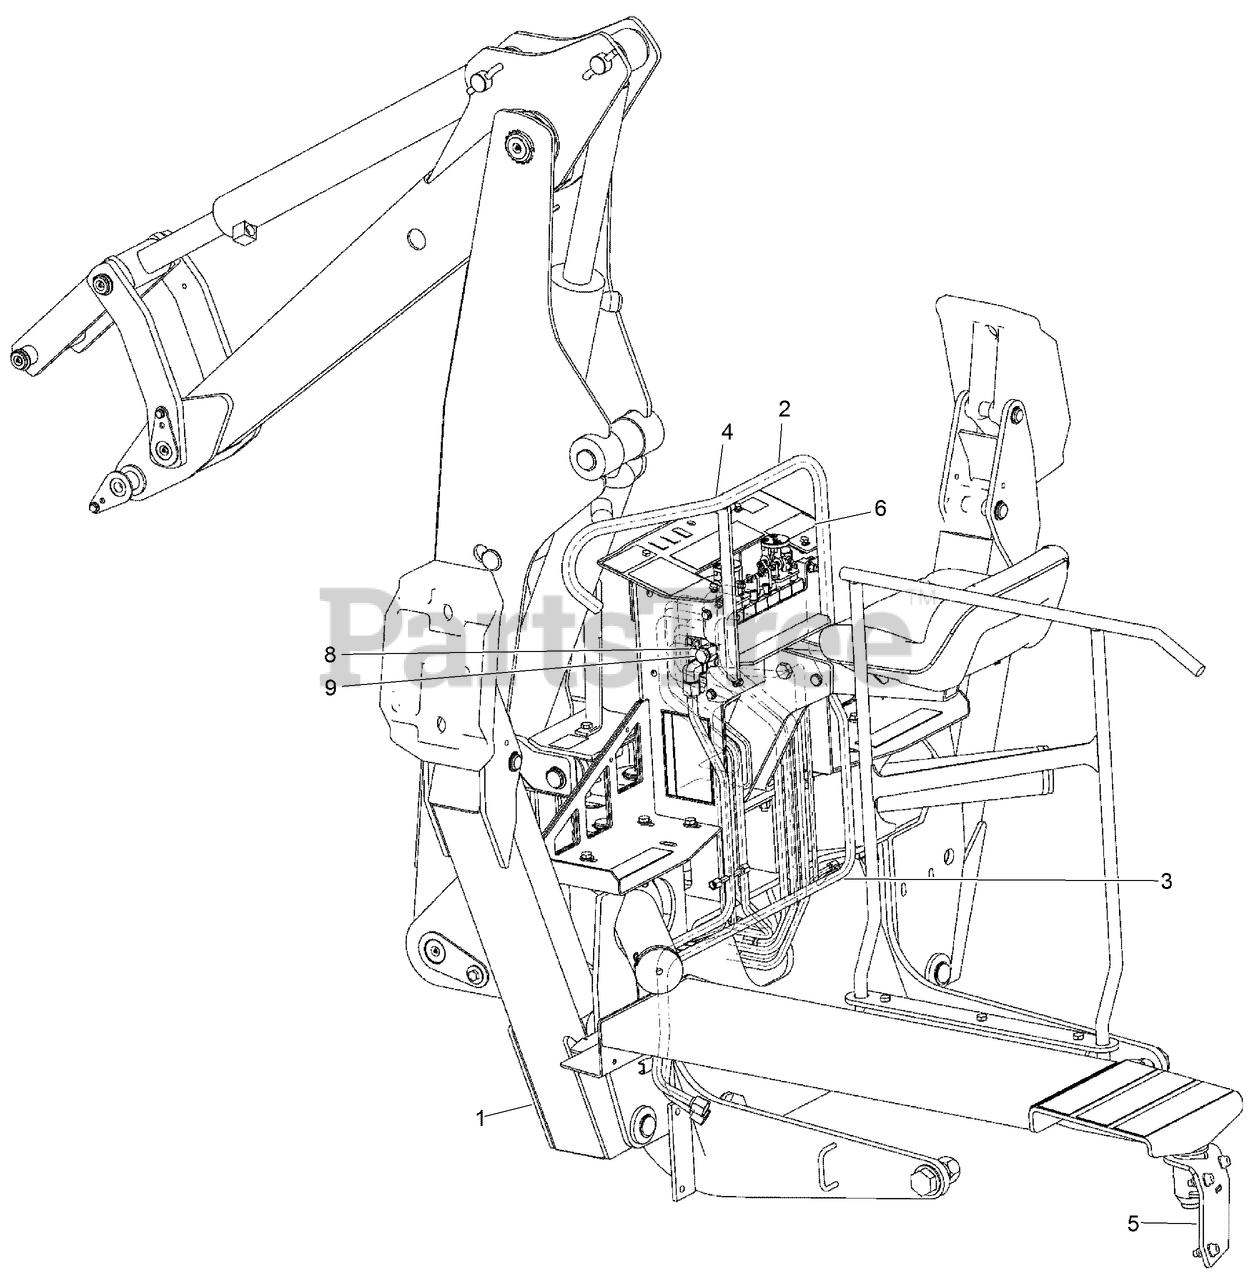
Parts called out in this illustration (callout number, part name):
1	ASSEMBLY - Basic Backhoe
2	ASSEMBLY - Backhoe Platform
3	KIT - Backhoe Plumbing
4	BUTTON-E-STOP
5	ASSEMBLY - Backhoe Walkway Kit
6	DECALS - Backhoe
8	FITTING-SLEEVE, POWER BEYOND
9	PLUG-HH
